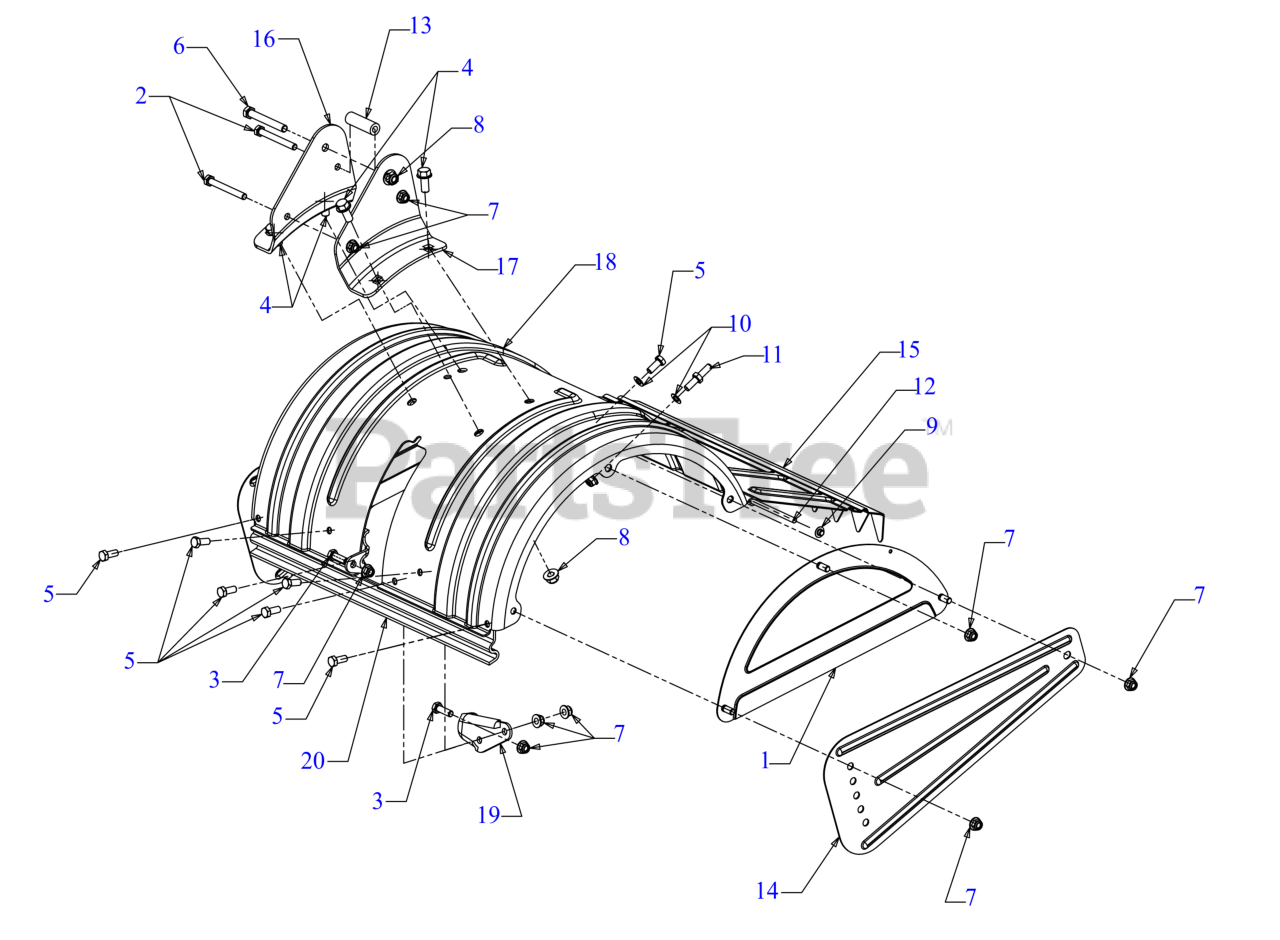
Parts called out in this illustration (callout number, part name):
2	HEX SCREW 5/16-18 x 2.75
3	SCREW 5/16-18 x 1.0 GR5
4	SCREW 3/8-16 x .875 GR5
5	SCREW 5/16-18 x .75 GR5
6	SCREW 3/8-16 x 2.75 GR5
7	FLANGE LOCK NUT 5/16-18
9	PUSH NUT
10	FLAT WASHER .344 ID x .62 OD x .033
11	SHOULDER SCREW 5/16-18X.75
12	TILLER FLAP ROD
13	SPACER
19	TINE SHIELD BRACKET
20	SHOULDER SPACER BRACKET
